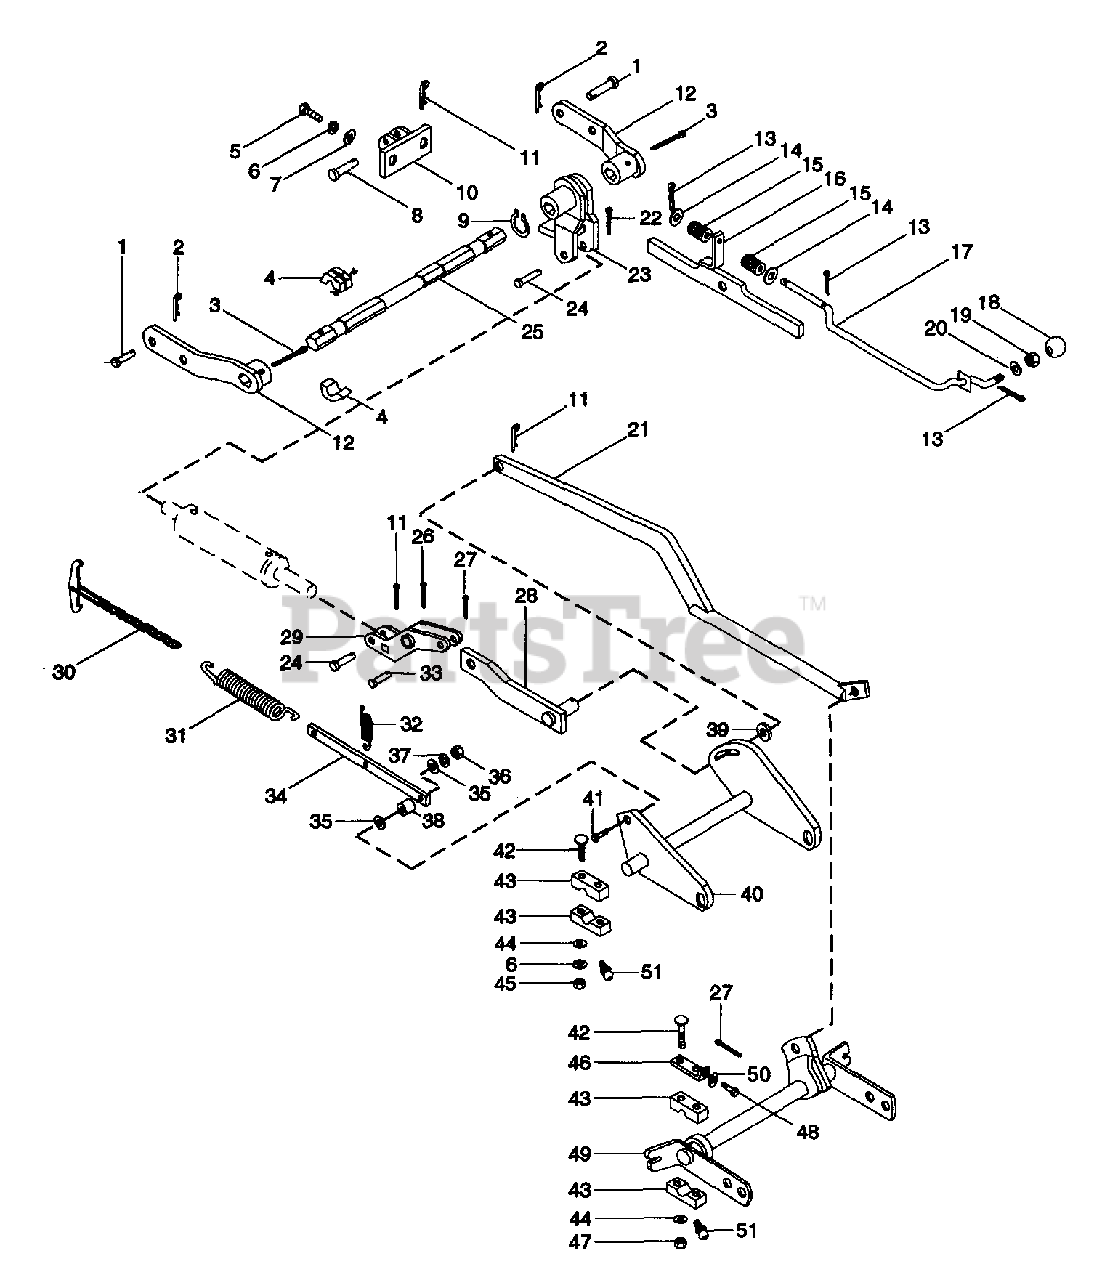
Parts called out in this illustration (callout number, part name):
1	PIN-CLEV .50X1.25 RH ST PL
2	PIN-HAIR INT .14X.4X2.75
3	PIN-COTR .18X2.0 ZCC
4	BSHG-FLG 1.000X1.750X1.000
5	BLT-HEX .38-16X1.00 PL
6	WSHR-LK .375X.094 MED PL
7	WSHR-FL-STL .438X1.0X.083 PL
8	PIN-CLEV .619X2.0 YWZC
9	RG-RTNG-EXT 1.125X.050
11	PIN-HAIR INT .09X.188 PL
13	PIN-COTR .12X.75 PL
14	WSHR-FL-STL.406X.812X.065PL
15	SG-COMP .65X.56X1.50
17	LATCH ROD
18	KNOB-STEERING LOCK
19	NUT-JAM .375-16 PL
20	WSHR-FL-STL .406X1.00X.062 PL
21	CONNECTOR LINK
22	PIN-COTR .12X1.0 PL
24	PIN-CLEV .494X1.94 YWZC
26	PIN-COTR .18X1.25 PL
27	PIN-COTR .18X1.0 PL
29	BELLCRANK
31	SG-TENS .156X1.062X8.68 WLD ??
32	SG-TENS .035X.45X2.75 WLD 3.5
33	PIN-CLEV .619X1.43 YWZC
35	WSHR-FL-STL.281X.62X.065 PL
36	NUT-HEX .250-20 PL
37	WSHR-LK .250X.077 HVY PL
38	SPACER .269X.375X.343
39	WSHR-FL-STL.812X1.500X.139
40	CENTER ROCKSHAFT
41	BLT-HEX .25-20X1.00 GR2
42	BLT-RDHDSQNK .38-16X2.25 SHTPL
44	WSHR-FL-STL .406X.750X.005
45	NUT-HEX .375-16
47	NUT-LK-CTR .375-16 GR A PL
48	BLT-HEX .31-18X1.25 PL GR5
49	ROCK SHAFT-FRONT
50	WSHR-LK .312X.097 PL HVY
51	SPIN DRIVE ZERK FITTING
